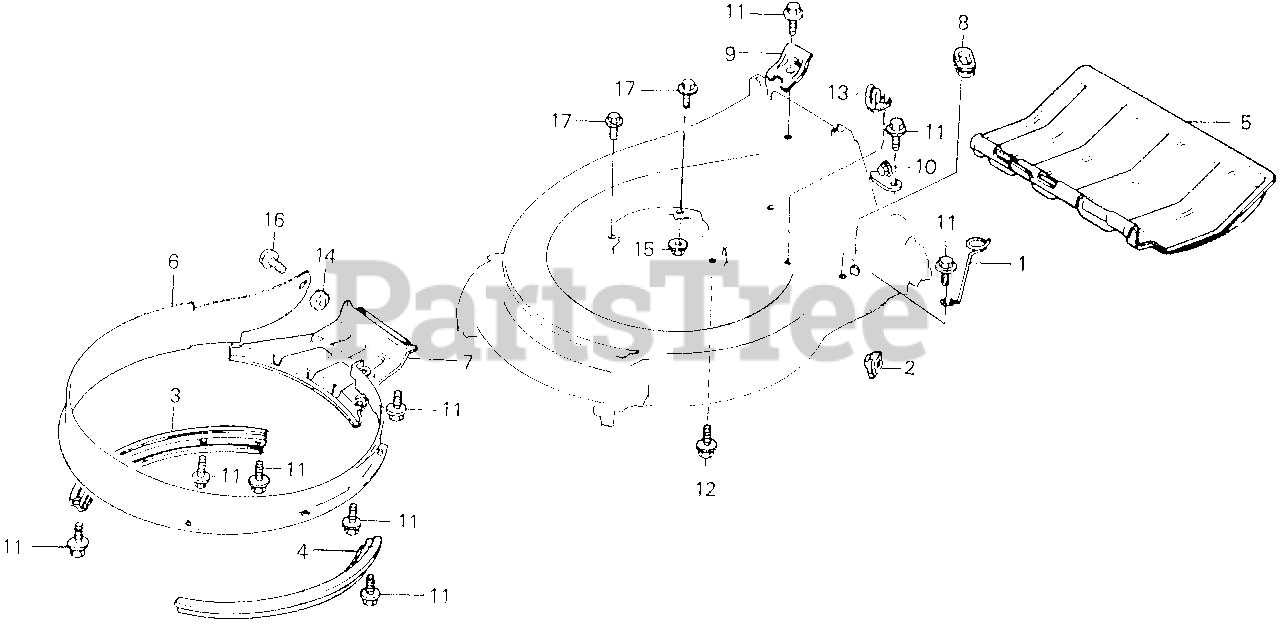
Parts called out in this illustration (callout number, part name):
1	GUIDE, CABLE (NOT AVAILABLE)
2	GROMMET, ROTO-STOP CABLE
3	GUARD, R. SAFETY
4	GUARD, L. SAFETY (NOT AVAILABLE)
5	SHIELD, SAFETY (NOT AVAILABLE)
6	LINE (INNER) (NOT AVAILABLE)
7	GUIDE, SCROLL (NOT AVAILABLE)
8	GROMMET, CABLE
9	PLATE, HOOK
10	STAY, PANEL
11	BOLT, FLANGE (6X12) (CT200)
12	BOLT, FLANGE UNF (5/16-24)
13	CLIP, WIRE
14	NUT, FLANGE (6MM)
15	NUT, FLANGE (8MM)
16	BOLT, FLANGE (6X16)
17	BOLT, FLANGE (8X40) (NOT AVAILABLE)
17	BOLT, FLANGE (8X40)
